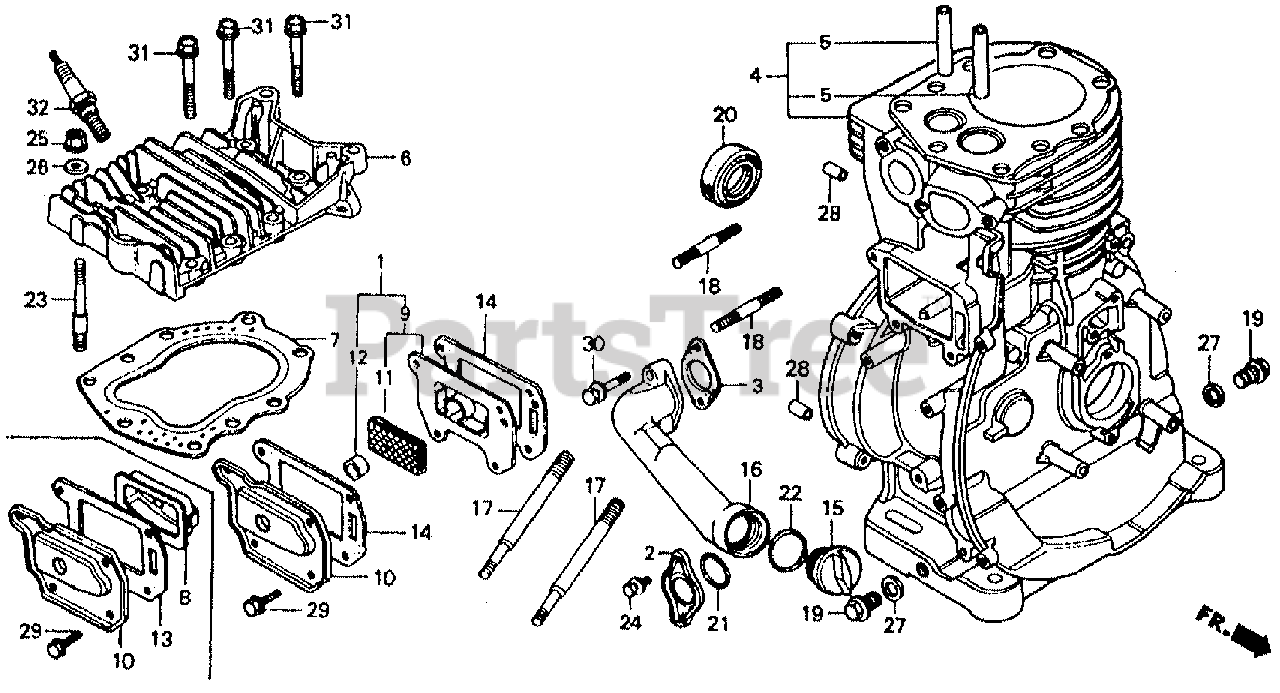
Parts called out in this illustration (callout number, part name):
1	CASE KIT, BREATHER (NOT AVAILABLE)
2	COVER, OIL PAN
3	GASKET, OIL PAN
4	CYLINDER (CRANKSHAFT P.T.O.) (NOT AVAILABLE)
4	CYLINDER (CRANKSHAFT P.T.O.)
5	GUIDE, VALVE
6	CYLINDER HEAD (NOT AVAILABLE)
7	GASKET, CYLINDER HEAD
8	CASE, BREATHER
9	CASE, BREATHER
10	COVER, TAPPET
11	FILTER, BREATHER
12	SEAL, BREATHER
13	GASKET, TAPPET COVER
14	GASKET, TAPPET COVER
15	CAP, OIL
16	PIPE, OIL
17	BOLT, STUD (8X104)
18	BOLT, STUD (8X35)
19	BOLT, DRAIN PLUG
20	OIL SEAL (30X46X8)
21	O-RING (27X2.0)
22	O-RING (26X2.7)
23	BOLT, STUD (10X70)
23	BOLT, STUD (10X60)
23	BOLT, STUD (10X40)
24	BOLT-WASHER (6X12)
25	NUT, FLANGE (10MM)
26	WASHER, PLAIN (10MM)
27	WASHER, DRAIN PLUG (12MM)
28	PIN A, DOWEL (8X14)
29	BOLT, FLANGE (6X12)
30	BOLT, FLANGE (6X25)
31	BOLT, FLANGE (10X55)
32	SPARK PLUG (B-4H)
32	SPARK PLUG (BR-4HS) (NGK)
32	SPARK PLUG (BP-4HS-10) (NGK)
32	SPARK PLUG (BPR-4HS-10) (NGK)
32	SPARK PLUG (BPR4HS-10) (NGK)
32	SPARK PLUG (BP4HS-10) (NGK)
32	SPARK PLUG (W14F-U) (DENSO)
32	SPARK PLUG (W14FR-U) (DENSO)
32	SPARK PLUG (W14FP-UL10) (DENSO)
32	SPARK PLUG (W14FPR-UL10) (DENSO)
32	SPARK PLUG (W20FS-U) (DENSO)
32	SPARK PLUG (W20FP-U10) (DENSO)
